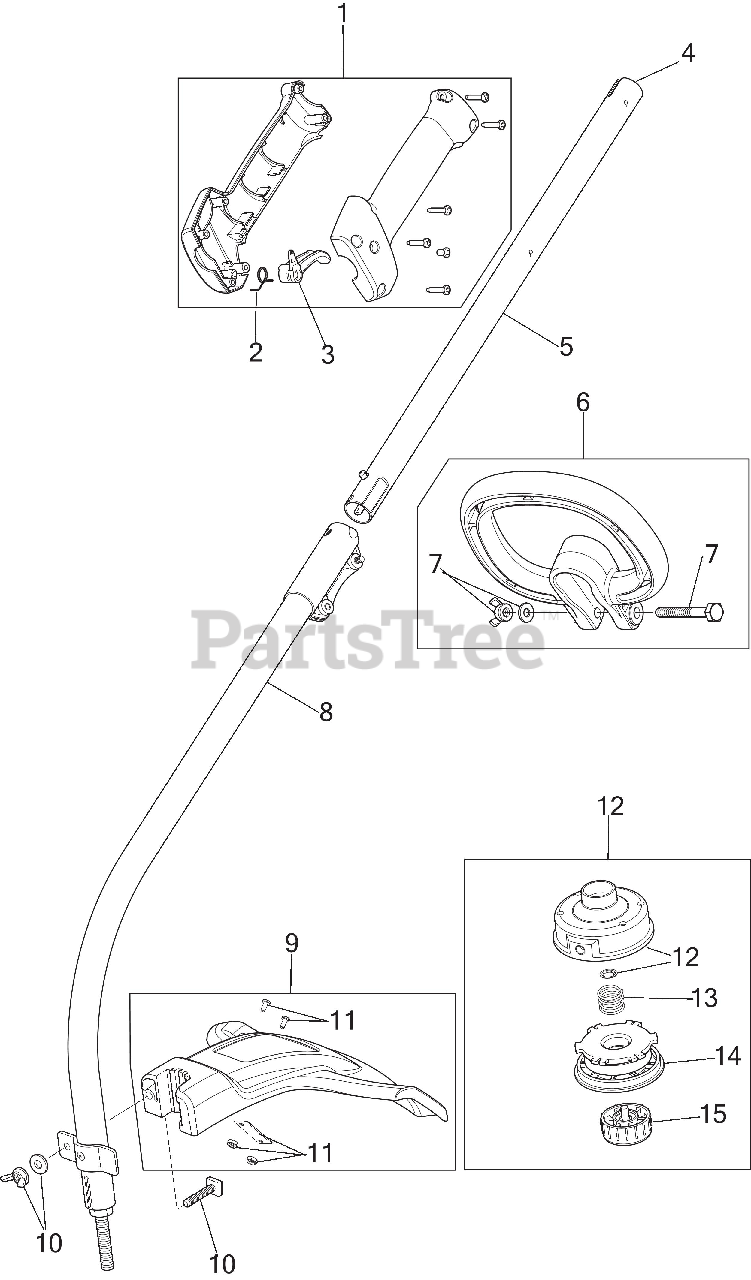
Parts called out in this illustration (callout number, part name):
1	THROTTLE GRIP ASSEMBLY
2	SPRING, TRIGGER
3	THROTTLE TRIGGER
4	UPPER SHFT
5	UPPER BOOM ASSEMBLY COM
6	HANDLE
7	HANDLE HWD
8	LOWER BOOM ASSEMBLY
9	GUARD ASSEMBLY
10	BLADE GUARD MOUNTING HARDWARE
11	BLADE:CUT OFF:LINE
12	REEL:OTR W/RET
13	SPRING-SPOOL
14	REEL-INNER SPOOL
15	BUMP HEAD KNOB ASSEMBLY
